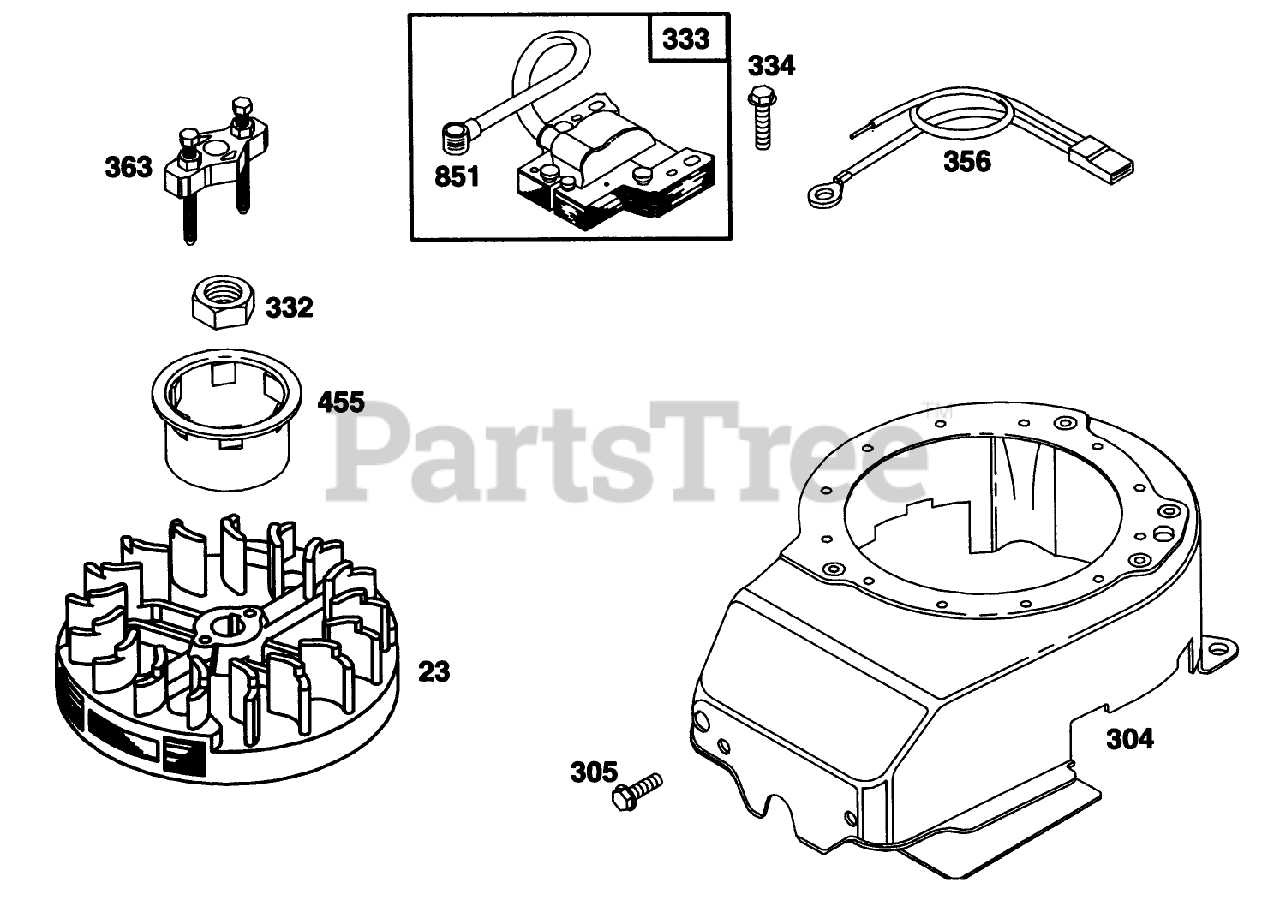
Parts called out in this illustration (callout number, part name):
23	Flywheel
304	Housing-Blower
305	Screw-Sem
333	Armature-Magneto
334	Screw
356	Wire Stop
363	Puller-Flywheel
455	Cup-Starter
851	Terminal-Cable
